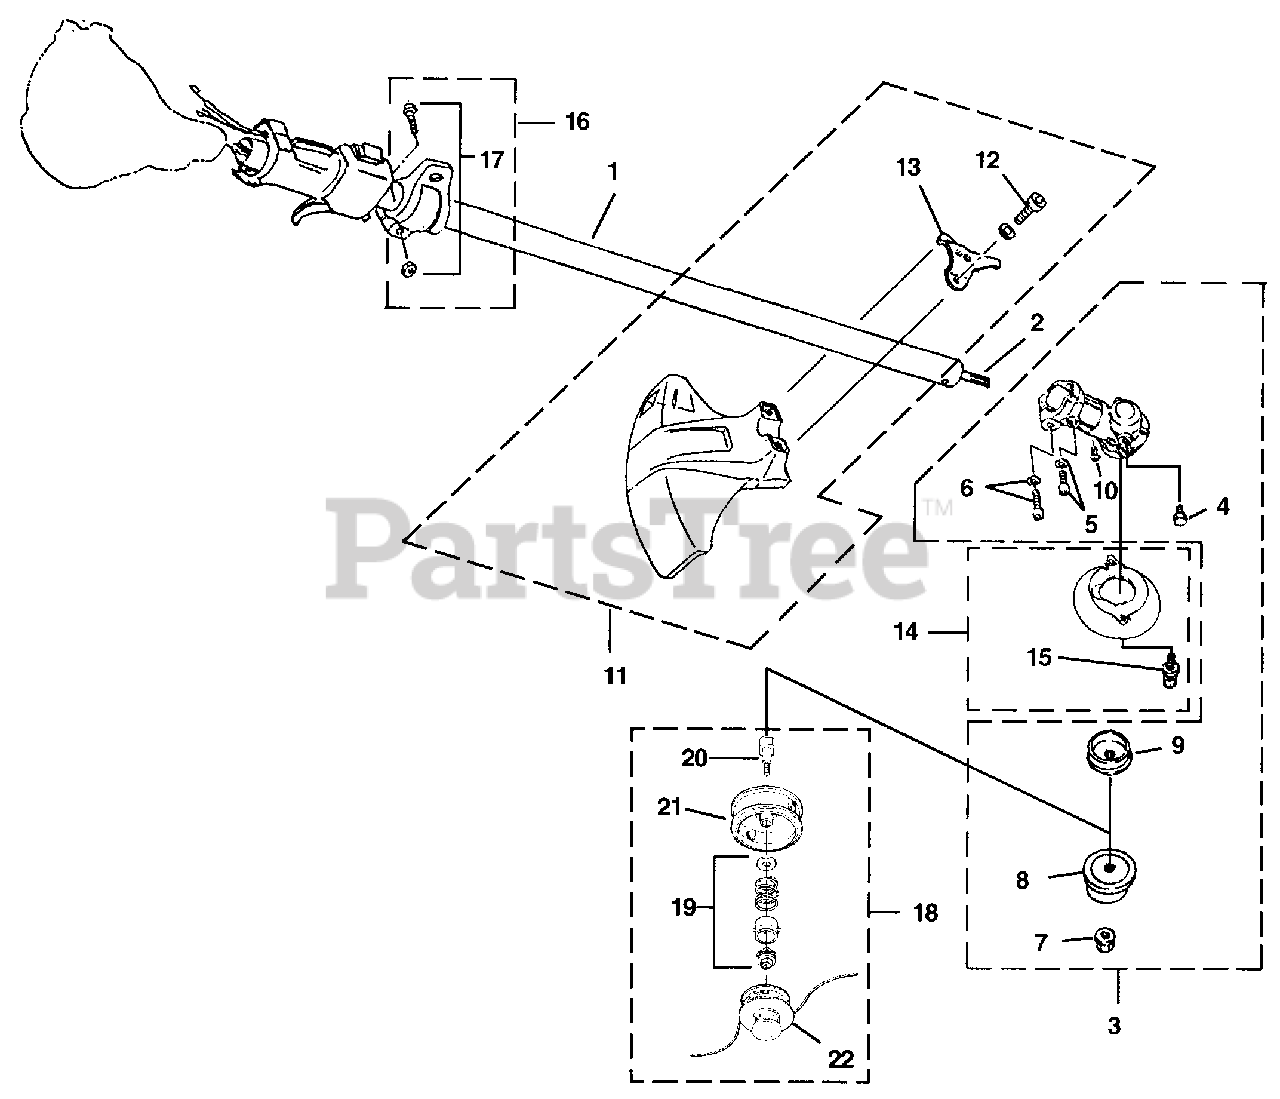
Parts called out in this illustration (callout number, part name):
1	DRIVESHAFT HOUSING
2	DRIVESHAFT
3	GEAR HEAD
4	BOLT-Grease (M8)
5	BOLT (M5 x 12 SW)
6	BOLT (M5 x 25 SW)
7	NUT (M8)
8	WASHER-Cupped
9	WASHER-Flange
10	SCREW (M5 x 6)
11	DEFLECTOR ASSEMBLY (Grass)
12	BOLT (M6 x 30)
14	GRASS GUARD
15	SCREW-Socket Hd (M5 x 12 W SW)
16	HANGER ASSEMBLY
17	SCREW and NUT (M5 x 20)
18	STRINGHEAD ASSEMBLY (.095)
19	REPAIR KIT
20	BOLT, Shaft
21	HOUSING W/Eyelets
22	SPOOL & STRING (.095)
